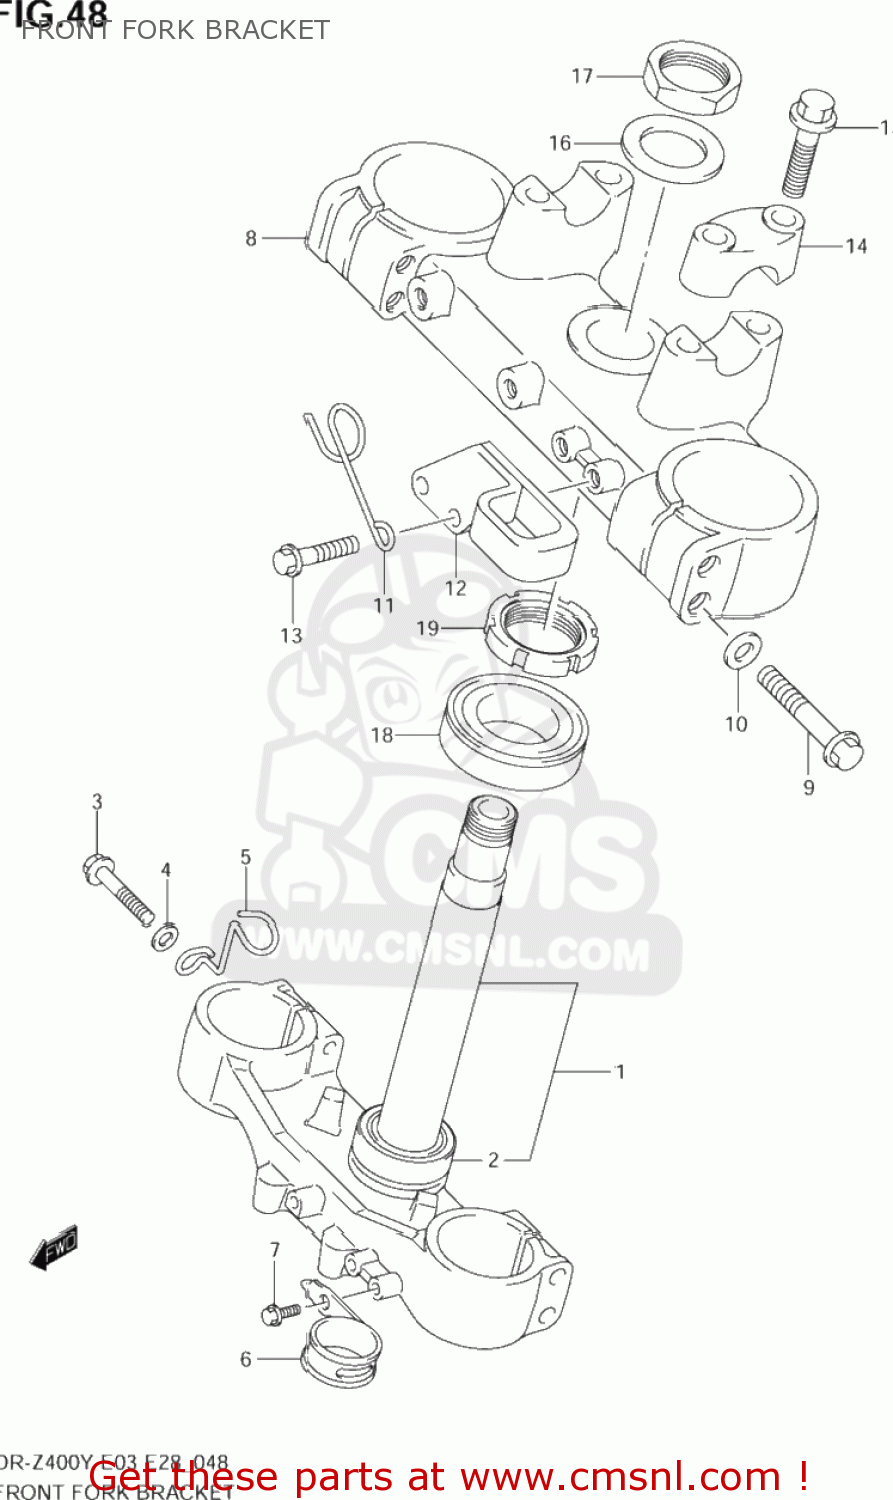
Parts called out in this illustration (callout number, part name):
1	BRACKET,FR FORK UNDER
2	BEARING(30X52X16)
3	BOLT
4	WASHER
5	GUIDE,SPEEDOMETER CABLE
6	GUIDE,CABLE
7	BOLT,PROTECTOR(6X10)
8	BRACKET,FR FORK UPR
9	BOLT
10	WASHER
11	GUIDE,CLUTCH CABLE
12	GUIDE,HOSE
13	BOLT
14	HOLDER,HANDLE
15	BOLT,HANDLE HOLDER(8X35)
16	WASHER,STEM HEAD
17	NUT,STEM HEAD
18	BEARING(30X52X16)
19	NUT,STEERING
